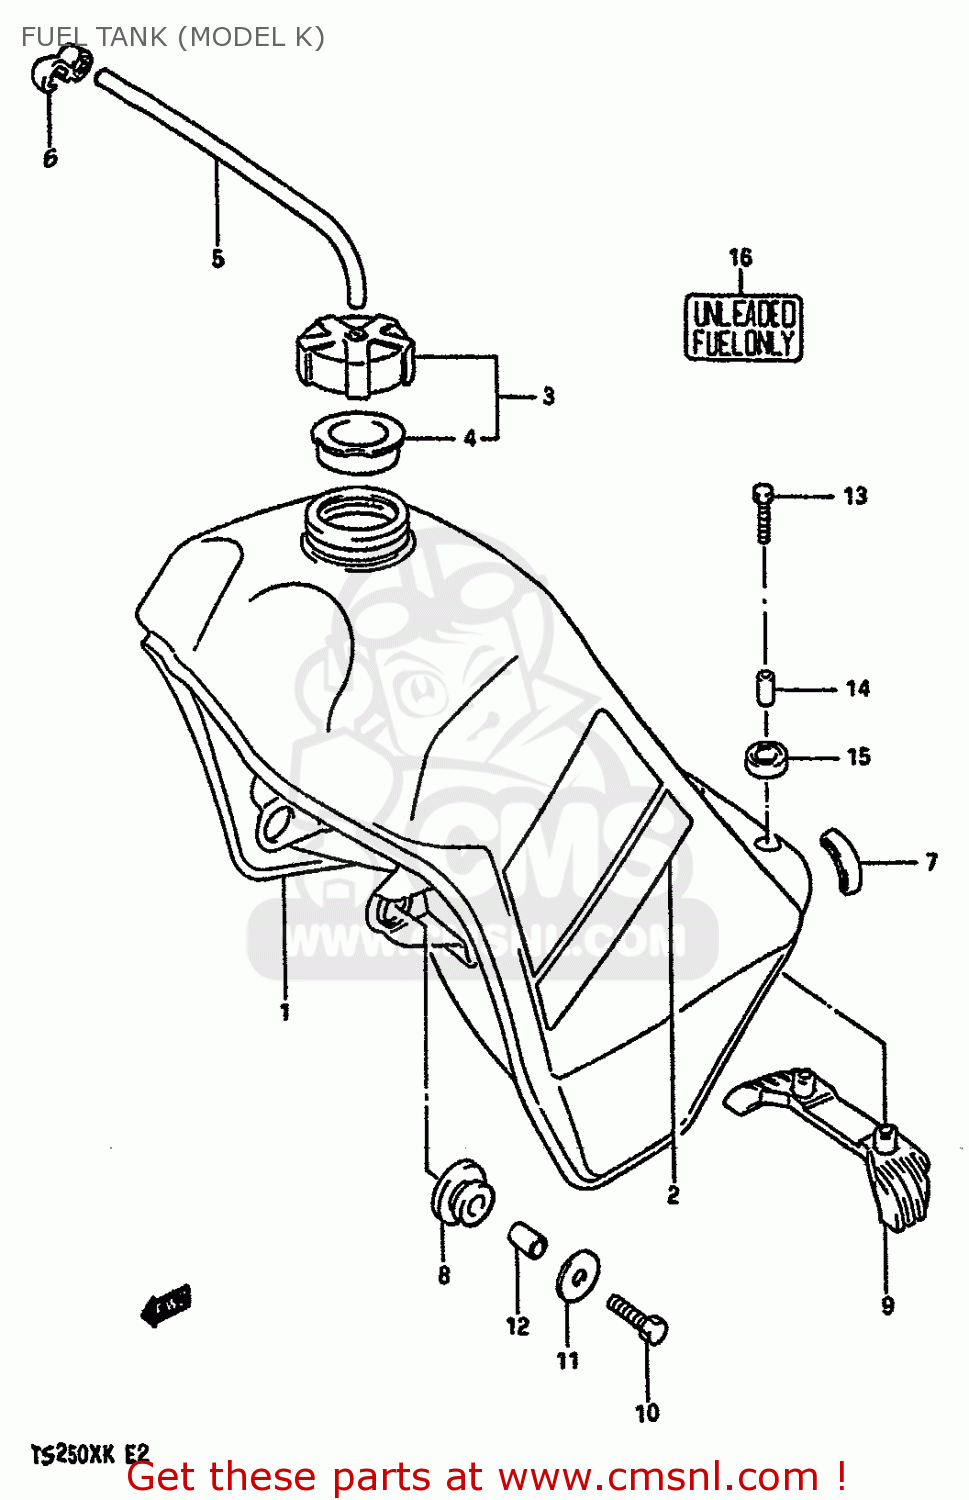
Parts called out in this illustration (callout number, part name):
1	TANK ASSY,FUEL (WHITE)
2	TAPE SET,FUEL TANK
3	CAP SET,FUEL TANK
4	GASKET (NAS)
5	HOSE
6	CLAMP,FUEL TANK BREATHER HOSE
7	MOLDING,FUEL TANK
8	CUSHION,FUEL TANK FRONT
9	CUSHION,FUEL TANK REAR LOWER
10	BOLT
11	WASHER
12	BOLT
13	BOLT
14	SPACER
15	BOLT
16	SPACER
17	CUSHION
18	LABEL,FUEL CAUTION
